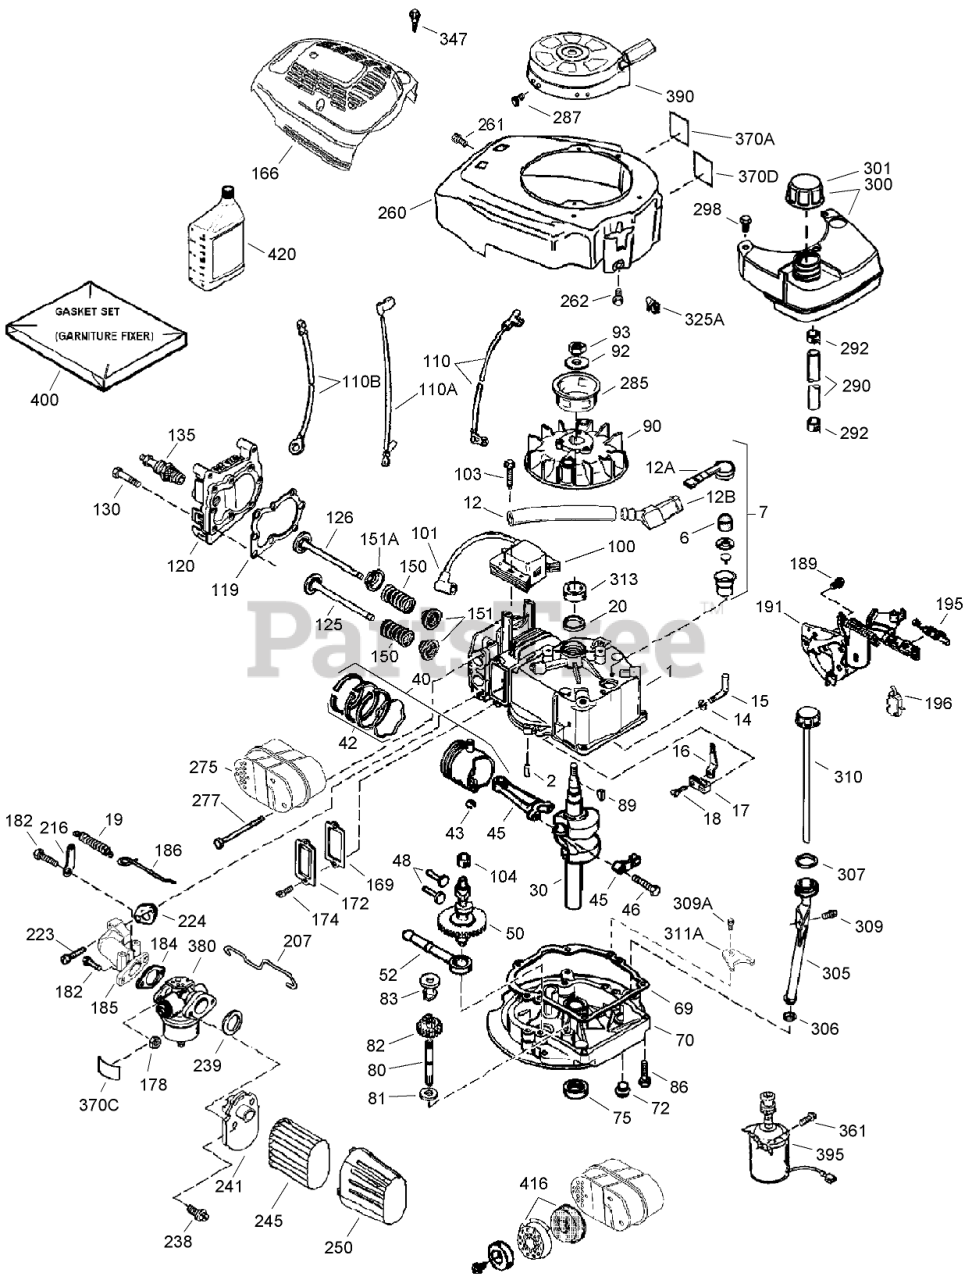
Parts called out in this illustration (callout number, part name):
310	Dipstick
311A	Bracket-Holddown
313	Spacer
325A	Clip-Actuator, Brake Switch
347	Screw (10-32 x 27/32)
361	Screw (1/4-20 x 1/2)
370A	Decal-Lubrication
370C	Decal-Primer
370D	Decal-Warning
380	Carburetor ASM (Includes 184)
390	Rewind Starter ASM (Note: This engine may have been built with 590702 starter)
395	12 Volt Electric Starter Motor ASM
400	Gasket Set
416	Spark Arrestor Kit
420	Oil-Engine (4-Cycle SAE 30)
